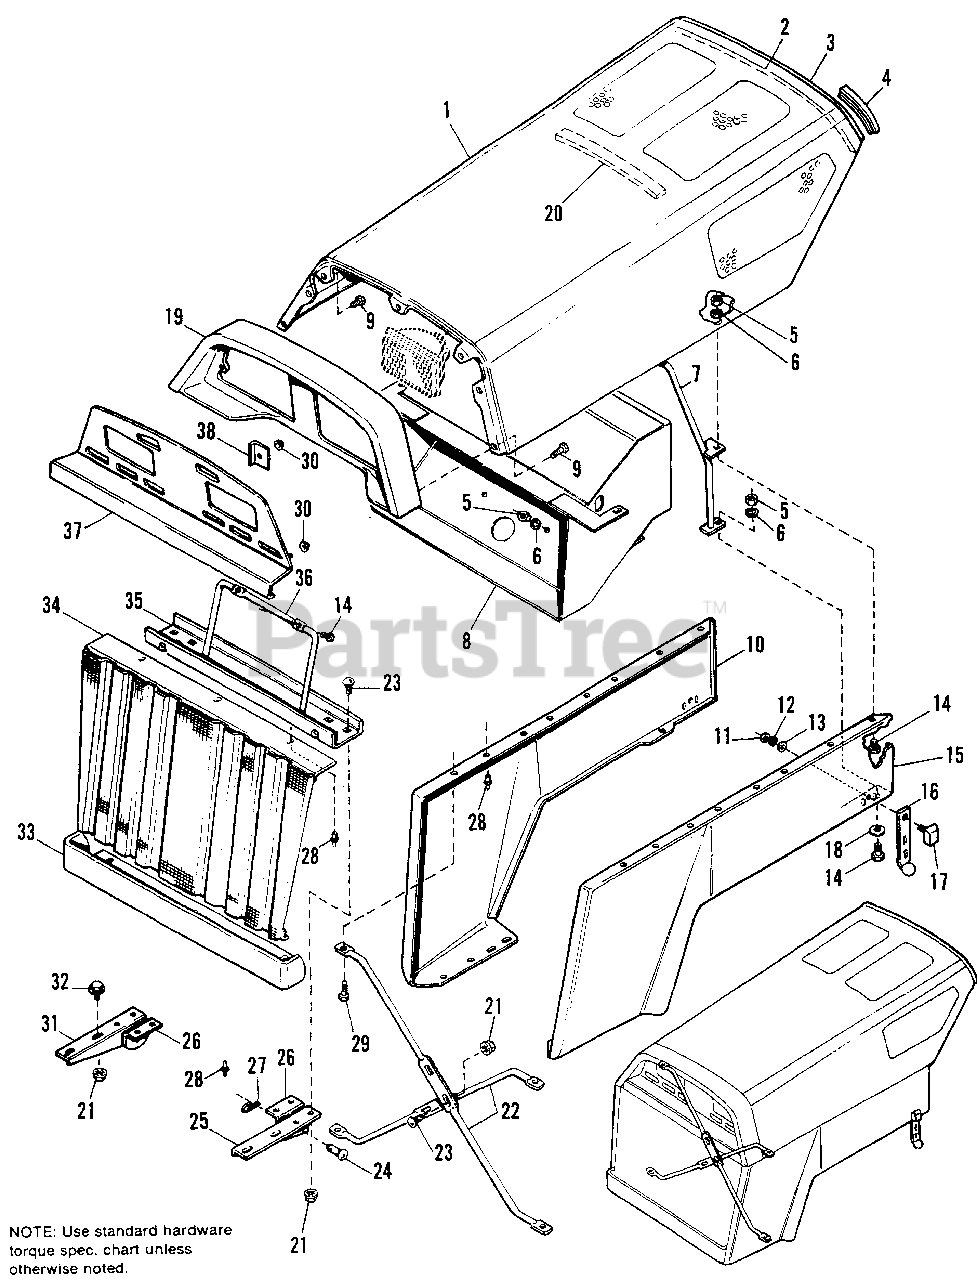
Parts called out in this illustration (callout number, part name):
2	SEAL, Hood, Rear
3	DECAL, Hood Rear
4	MOLDING, Hood
5	NUT, Hex, 1/4-20
6	LOCKWASHER, 1/4
7	SUPPORT ROD ASSY., Hood
8	SHIELD ASSY.
9	SCREW, Hex, Taptite, 1/4-20 x 1/2
10	PANEL, Side, R.H.
11	NUT, Hex, #10-24
12	LOCKWASHER, #10
13	WASHER, 13/64 ID x 3/4
14	CAPSCREW, Hex Hd., 1/4-20 x 1/2
15	PANEL, Side, L.H.
16	STRAP, Hood
17	COVER ASSY., Hood Strap
18	WASHER, Plain, 1/4 x 5/8 x 3/64
19	FRAME, Headlamps
20	SEAL, Hood Support
21	NUT, Hex, Flange Whizlock 1/4-20
22	BRACE, Hood, Front
23	BOLT, Carriage, 1/4-20 x 3/4
24	PIN, Lock (Clevis)
25	HINGE, Hood, Outer, L.H.
26	HINGE, Hood, Inner
27	PIN, Quick, 3/32 x 1-7/8
28	RIVET, Pop, 3/16
29	SCREW, Hex, Thd. Form, #14-3/4
30	PALNUT, Hex, Lock, #10-24
31	HINGE, Hood, Outer, R.H.
32	SCREW, Hex, Fl. Whiz Lock, 1/4-20 x 3/4
33	BUMPER ASSY.
34	SCREEN ASSY., Grille
35	SUPPORT, Stop, Hood
36	SUPPORT, Muffler Shield
37	INSERT ASSY., Headlamps
38	CLIP, Headlamps, Mounting
